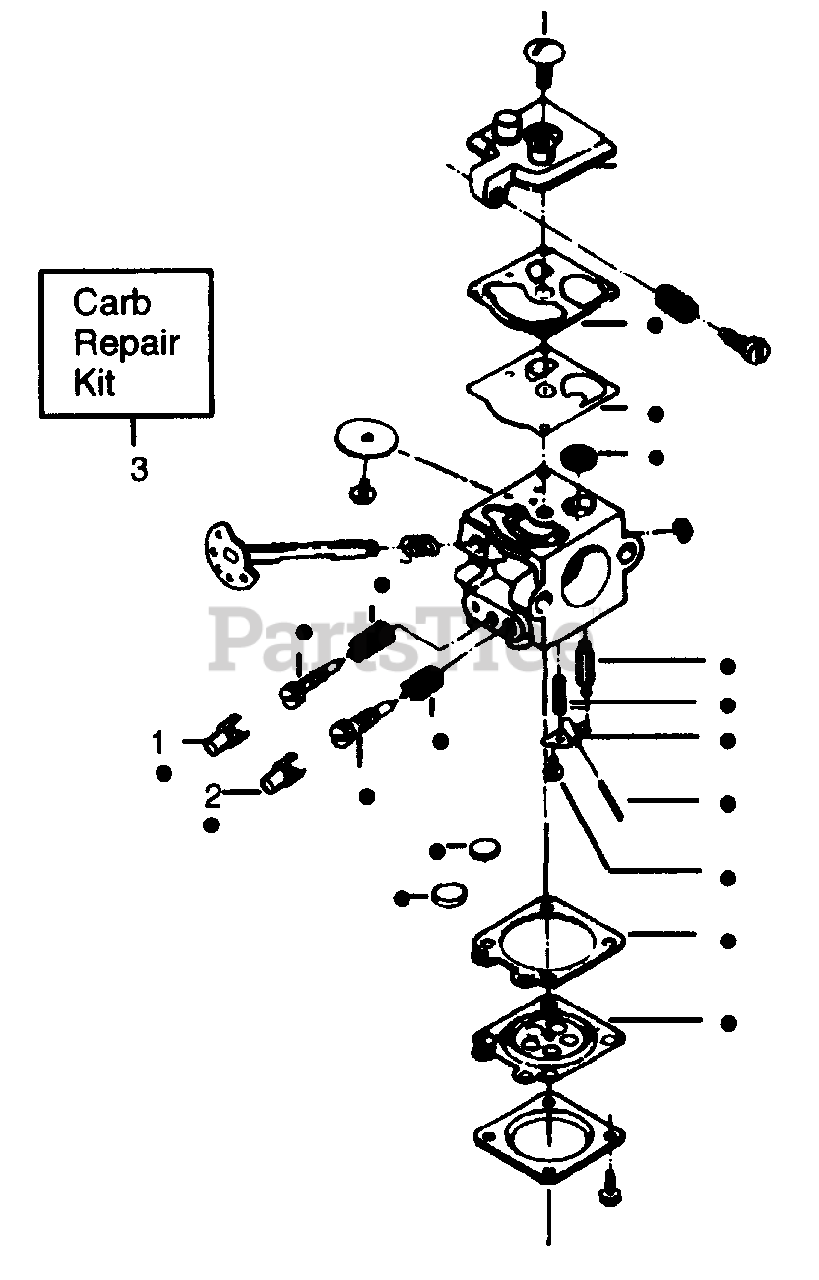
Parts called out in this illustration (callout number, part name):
1	Limiter Cap-High
2	Limiter Cap-Low
3	Carburetor Repair Kit (ù Indicates Contents)
